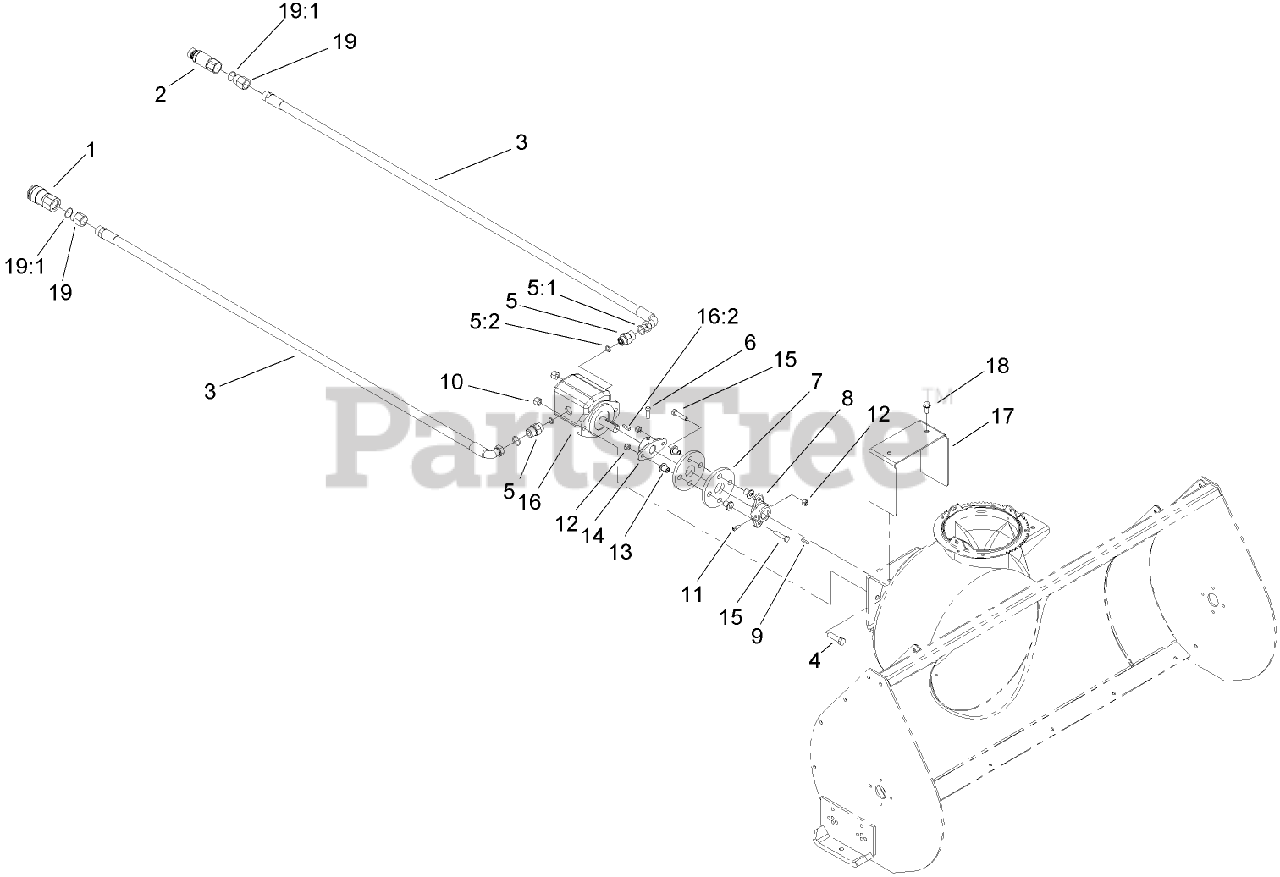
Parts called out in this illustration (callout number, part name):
1	COUPLER-FACE, FLUSH
2	NIPPLE-CONNECT, PRESSURE
3	HOSE-HYD
4	SCREW-HH
5	FITTING-STRAIGHT
5:1	O-RING
5:2	O-RING
6	SCREW-SET
7	COUPLING-RUBBER
8	HUB-COUPLER
9	KEY
10	NUT-LOCK, NI
11	SCREW-SET, SQH
12	NUT-LOCK, NI
13	SPACER
14	HUB-PUMP
15	SCREW-HH
16	MOTOR-HYDRAULIC
16:2	KEY-SQUARE
17	SHIELD-MOTOR
18	SCREW-HWHTF
19	ADAPTER-HYD
19:1	O-RING
